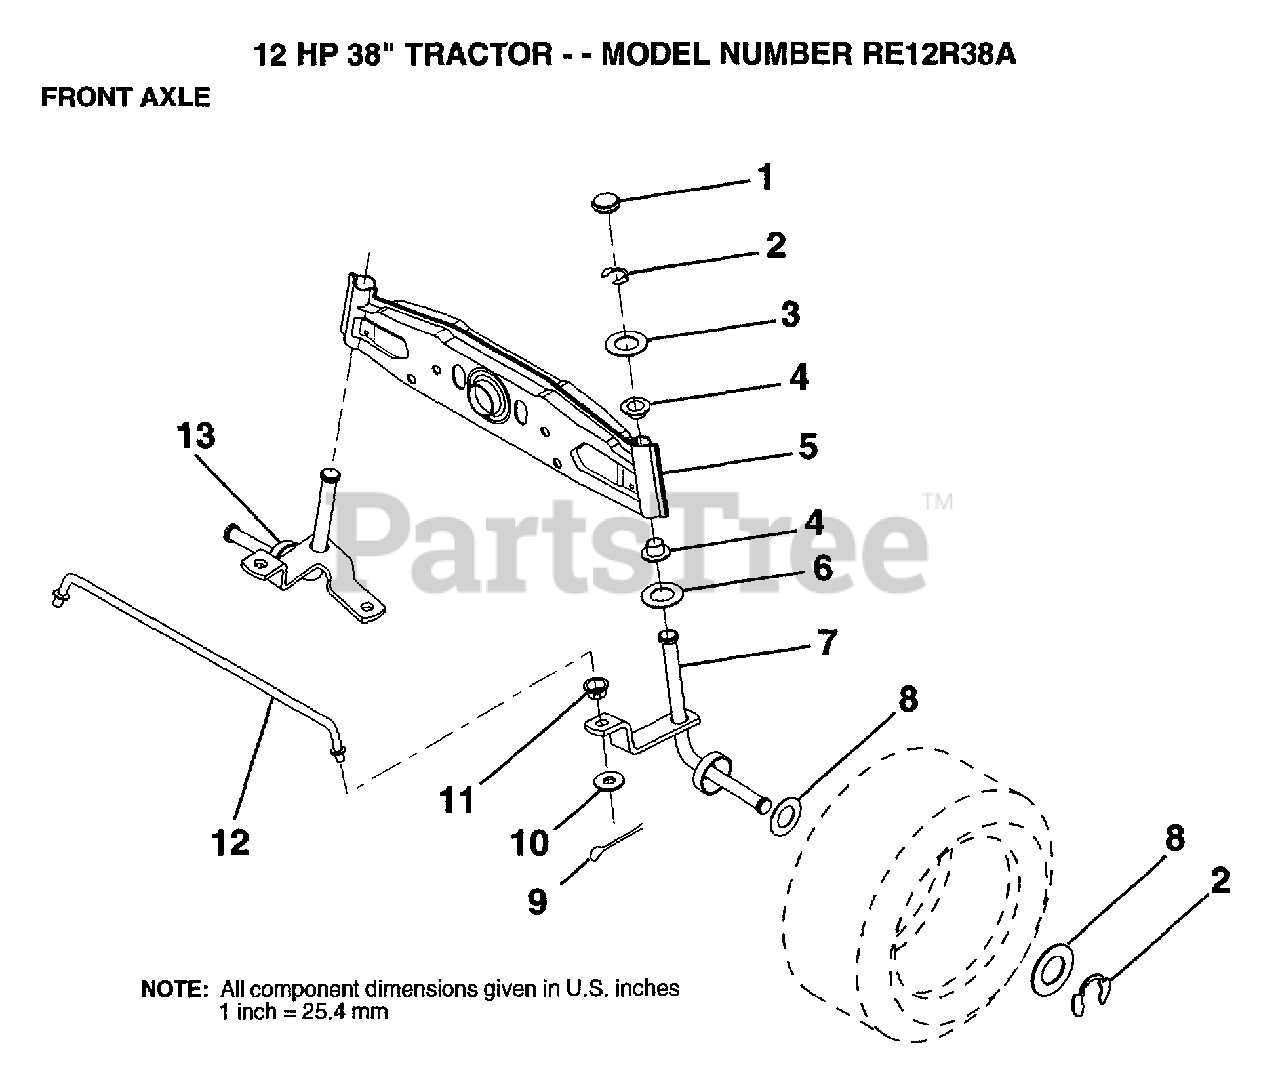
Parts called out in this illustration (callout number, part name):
1	CAP
2	RING
3	WASHER
4	NYLINER (12L12SK-1)
6	WASHER .T
8	WASHER (2513009)
9	COTTER PIN
10	WASHER
11	BUSHING.DRAGLINK (3 2)
